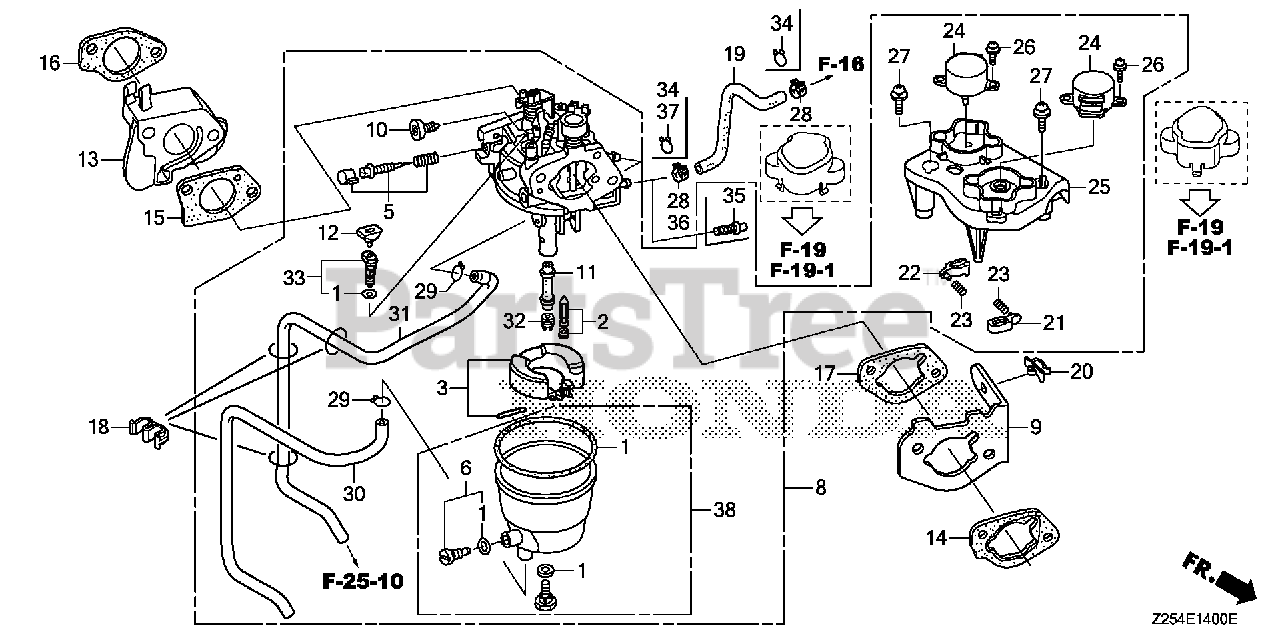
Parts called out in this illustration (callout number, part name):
1	GASKET SET
2	VALVE SET, FLOAT
3	FLOAT SET
4	CHAMBER SET, FLOAT
5	SCREW SET (Honda Code 4219879). (CARBURETOR NO.)
6	SCREW SET, DRAIN (ADVENTURE GREEN) (CARBURETOR NO.)
7	SCREW SET
8	CARBURETOR ASSY. (BE89G A)
9	HOLDER, TUBE
10	SCREW, STOP
11	NOZZLE, MAIN
12	COLLAR, SET
13	INSULATOR, CARBURETOR
14	SPACER, CARBURETOR
15	GASKET, CARBURETOR
16	GASKET, INSULATOR Use up to Engine SN 2949254.
17	GASKET, AIR CLEANER
18	CLAMP, TUBE (7.5X2)
19	TUBE, FUEL TANK (FKM) (ENGINE NO.)
20	CLIP B, HARNESS
21	LEVER, LINK
22	LEVER, LINK (CARBURETOR NO.)
23	SPRING, COMPRESSION COIL (CARBURETOR NO.)
24	MOTOR, THROTTLE CONTROL
25	BRACKET, THROTTLE MOTOR
26	SCREW-WASHER (3X8)
27	SCREW-WASHER (4X12) Use up to Engine SN 2056819.
28	CLIP, TUBE (D8)
29	CLIP, TUBE (4.5)
30	BULK HOSE, VINYL (4.5X8X1000) (4.5X8X750)
31	BULK HOSE, VINYL (4.5X8X1000) (4.5X8X750)
32	JET, MAIN (#92)
32	JET, MAIN (#95)
32	JET, MAIN (#98) Use from Engine SN BE87A A to BE87A A.
33	JET SET, PILOT (#40) (ADVENTURE GREEN) (CARBURETOR NO.)
38	BOLT KIT, FUEL CHAMBER (CARBURETOR NO.)
38	BOLT KIT
38	BOLT KIT, FUEL CHAMBER
